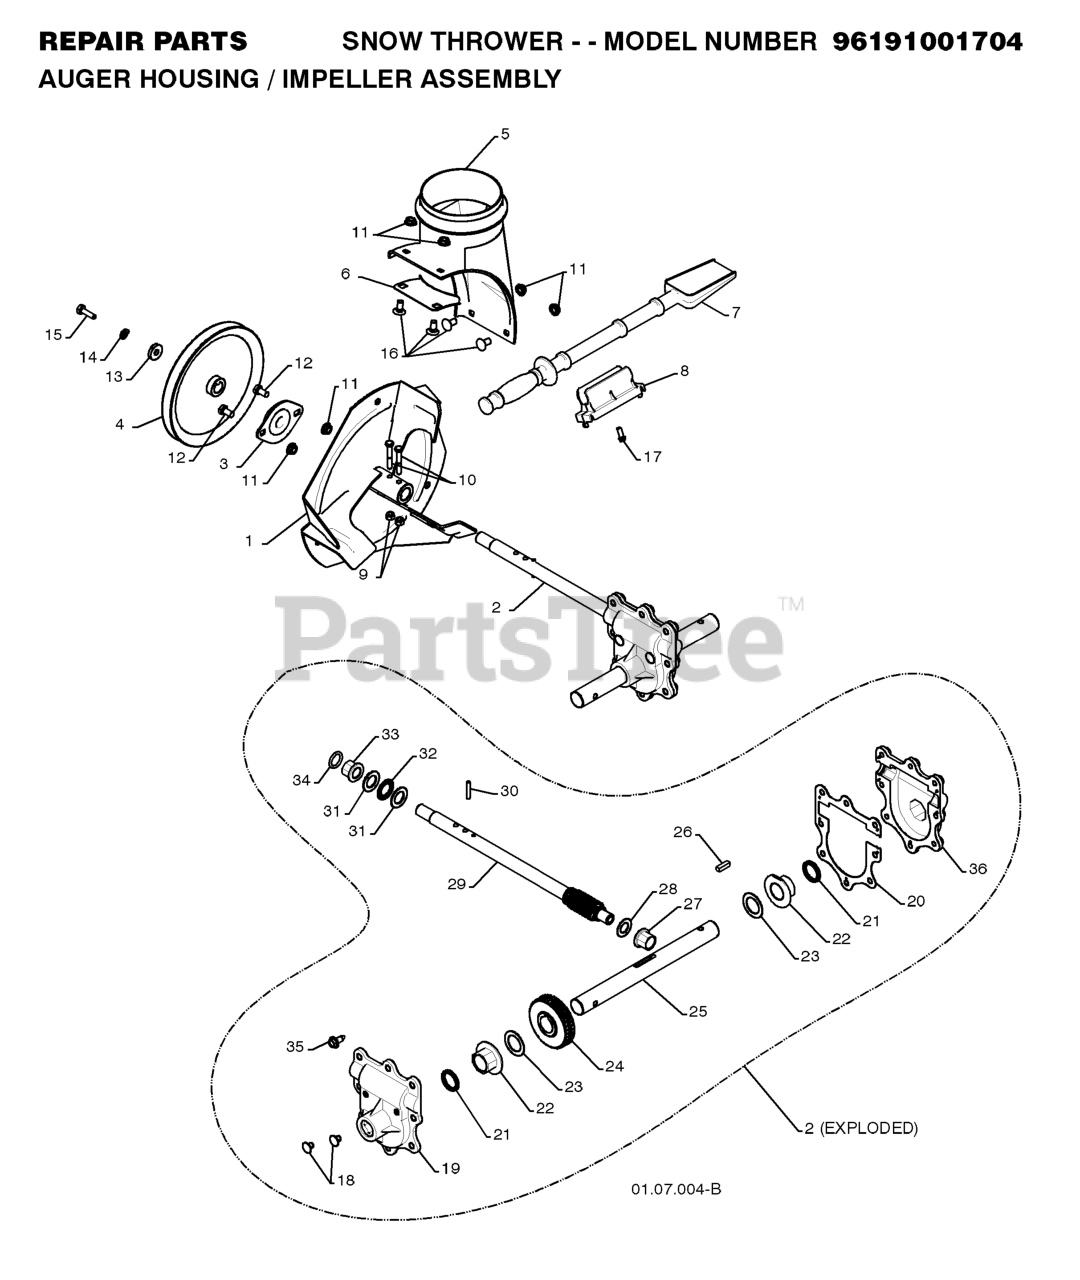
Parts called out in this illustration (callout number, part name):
1	IMPELLER ASSY
2	GEARBOX.ASSEMBLY.AUGER
3	BEARING FLANGE
4	PULLEY, IMPELLER
5	BASE DISCHARGE CHUTE
6	BRACKET, CORNER DISCHARGE
7	CLEAN OUT TOOL
8	CLIP.CLEANOUT.TOOL
9	LOCKNUT.NYLOC.1/4-20
10	SCREW.HEX.HD1/4-20X
11	NUT.FLANGE.5/16
12	BOLT, HEX HEAD 5/16-18
13	WASHER, FLAT
14	WASHER.LOCK.HVY.HLCL.SPR.5/16
15	CAPSCREW.HX.HD.5/16-18X1.00.NY
16	BOLT.CARRIAGE.5/16-18X
17	SCREW.HWH.13-16-5.8.BZP
18	CASE PLUG
19	GEARBOX HOUSING-RH
20	GEARBOX GASKET
21	OIL SEAL
22	FLANGE BUSHING-1"
23	WASHER TRUST 1"
24	WORM GEAR
25	AUGER SHAFT
26	KEY, SQUARE 1/4 X .875
27	FLANGE BUSHING-5/8
28	WASHER, THRUST 5/8
29	SHAFT, IMPELLER
30	PIN, ROLL 3/16 X 1-1/8
31	WASHER, THRUST 3/4
32	BEARING TRUST 3/4 NTA-1220
33	BUSHING, FLANGE 3/4
35	HEX SCREW-5/16 X 3/4
36	HOUSING.GEARBOX.LH(SERVICE)
